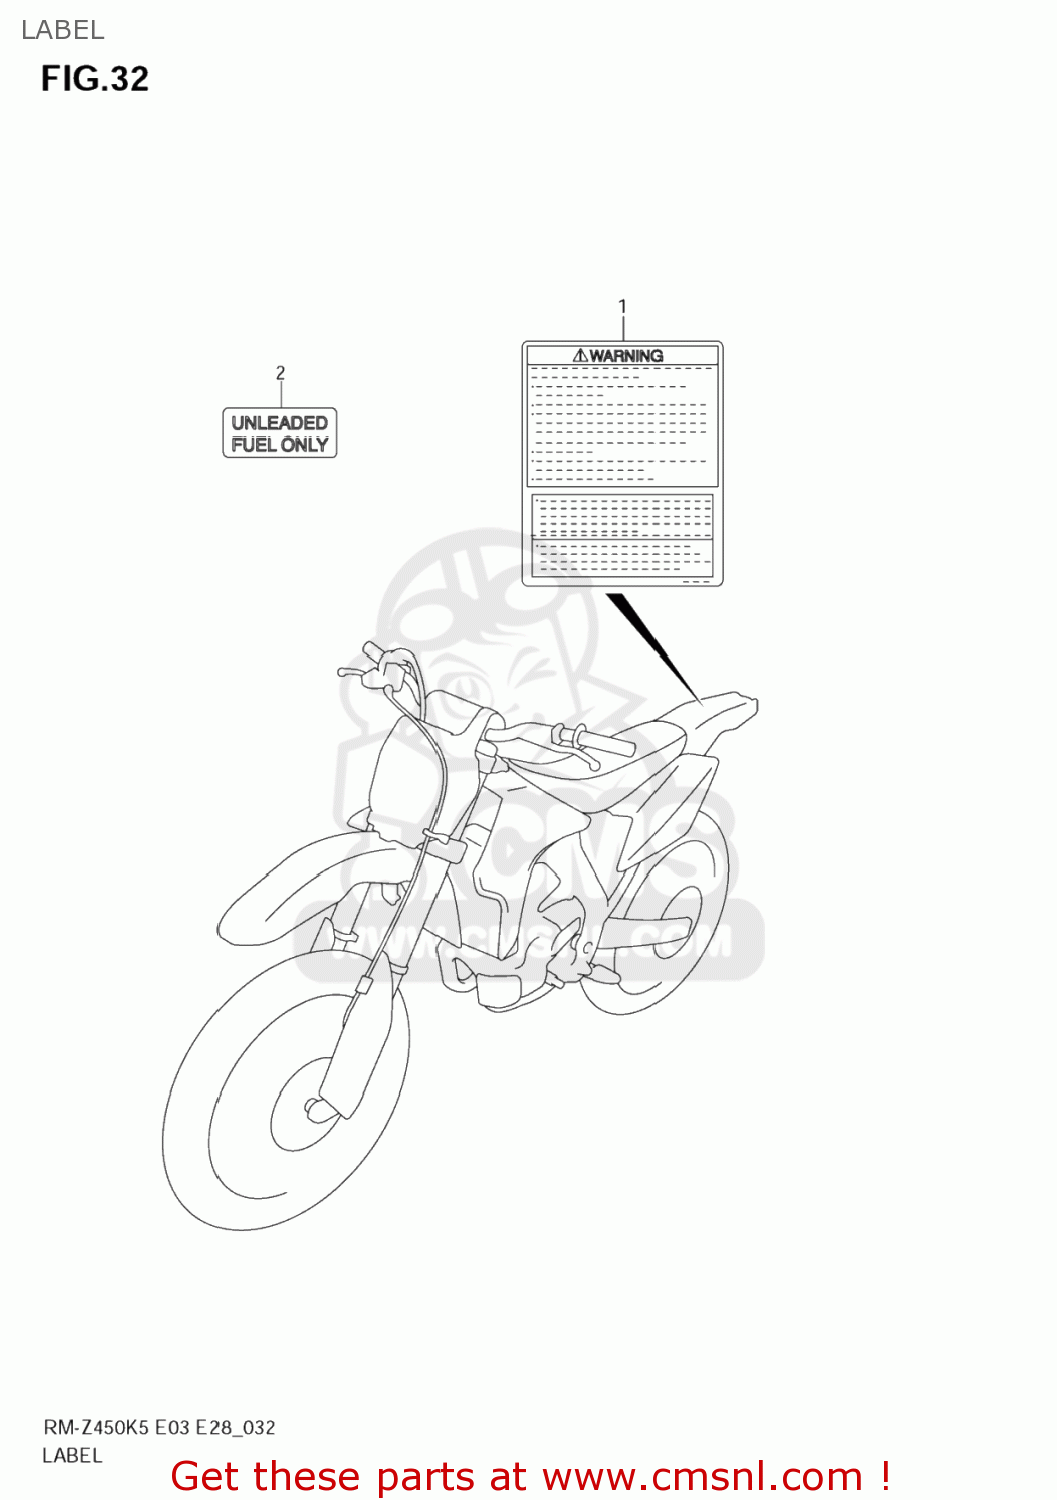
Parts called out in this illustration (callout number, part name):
1	LABEL,WARNING
2	LABEL,UNLEADED FUEL
3	MANUAL,OWNER'S
